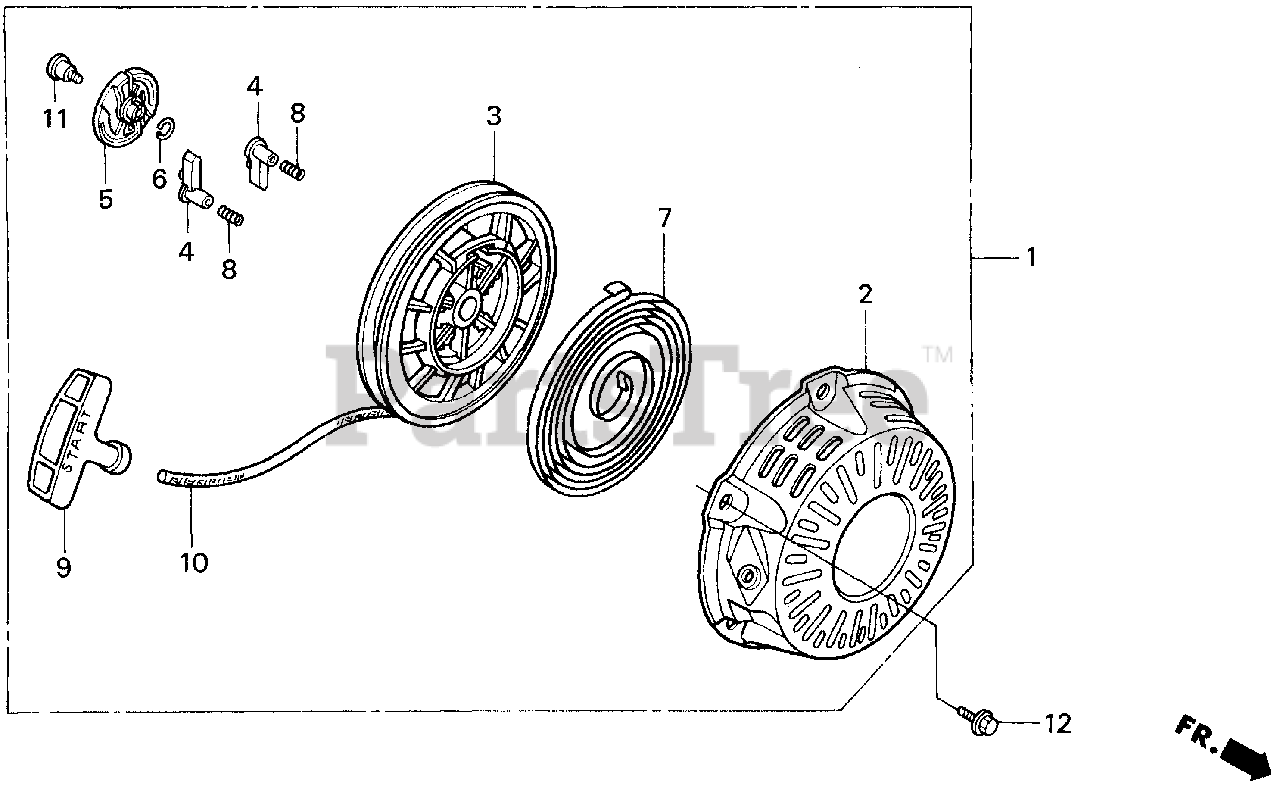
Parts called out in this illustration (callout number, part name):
1	STARTER ASSY., RECOIL *R8* (BRIGHT RED)
1	STARTER ASSY., RECOIL *NH1* (BLACK)
2	CASE, RECOIL STARTER *R8* (BRIGHT RED)
2	CASE, RECOIL STARTER *NH1* (BLACK)
3	REEL, RECOIL STARTER
4	RATCHET, STARTER
5	GUIDE, RATCHET
6	SPRING, FRICTION
7	SPRING, RECOIL STARTER
8	SPRING, RETURN
9	KNOB, RECOIL STARTER
10	ROPE, RECOIL STARTER (NA USE ALT:08550-ZG921-11)
11	SCREW, SETTING
12	BOLT, FLANGE (6X10)
